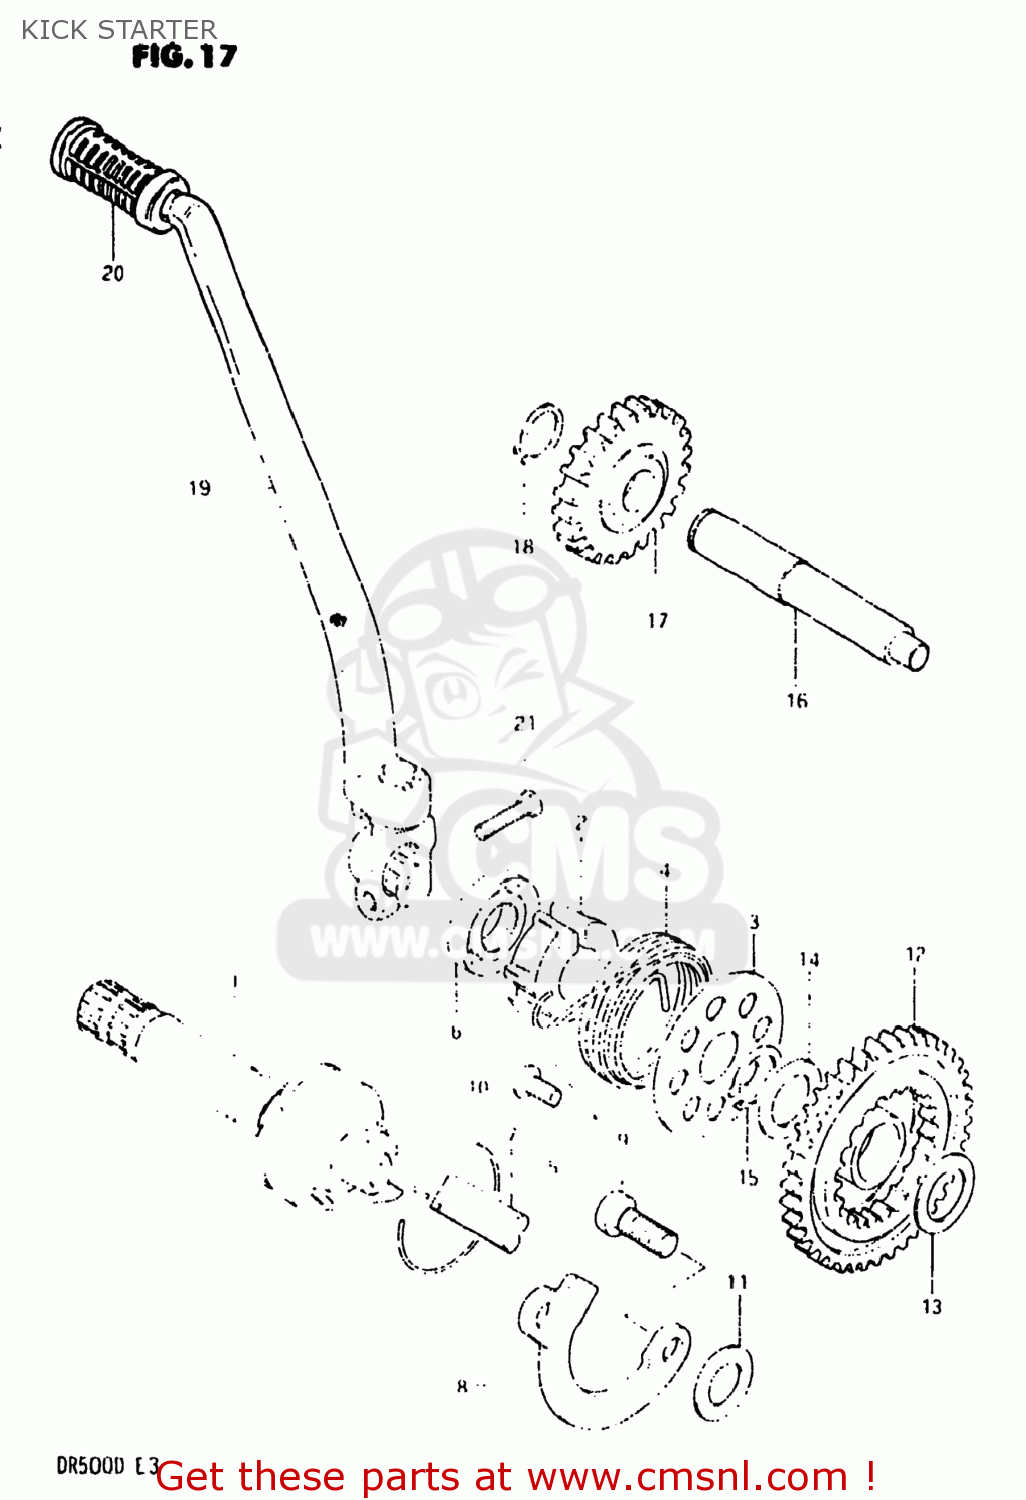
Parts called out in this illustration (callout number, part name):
1	SHAFT,KICK STARTER
2	GUIDE,KICK SHAFT SPRING
3	HOLDER,KICK SHAFT SPRING
4	SPRING
5	SCREW
6	SEAL,OIL(20X37X7)
7	PAWL,KICK STARTER
8	LIFTER,KICK STARTER
9	STOPPER,KICK STARTER
10	SPRING,KICK START PAWL RETURN
11	WASHER
12	GEAR,KICK STARTER DRIIVE
13	WASHER
14	WASHER,THRUST
15	CIRCLIP
16	SHAFT,KICK STARTER IDLE
17	GEAR,KICK STARTER IDLE
18	CIRCLIP
19	LEVER ASSEMBLY,KICK STARTER
20	RUBBER,KICK STARTER PEDAL
21	BOLT 8X25
